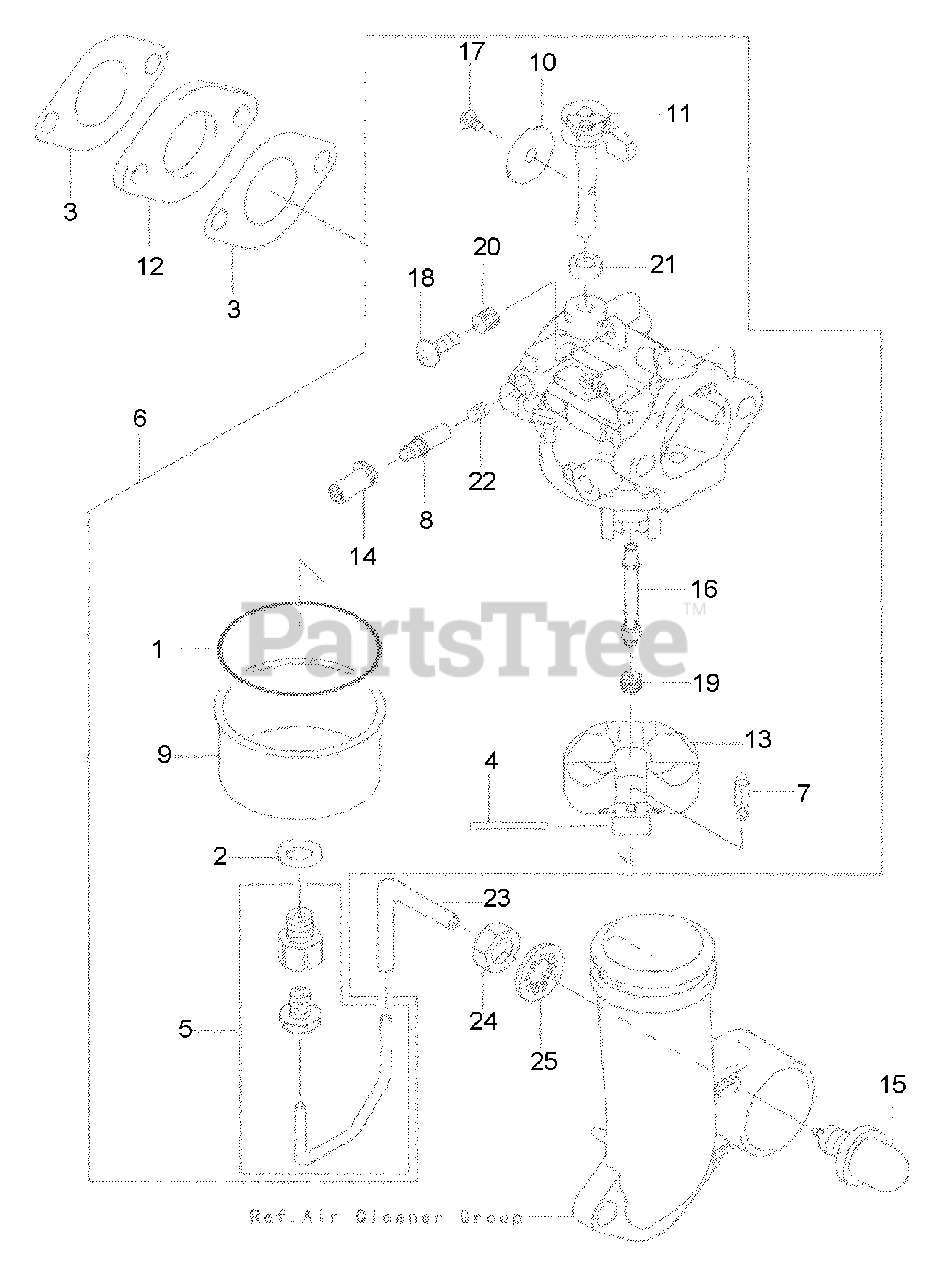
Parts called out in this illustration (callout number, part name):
3	Gasket
5	Bushing Assy.
6	Carburetor Assy.
8	Pilot Air Screw
10	Throttle Valve
11	Throttle Shaft
12	Insulator
19	Main Jet, #76
23	Tube, 2x5x65
24	Hex Nut, Fine
25	Toothed Washer
